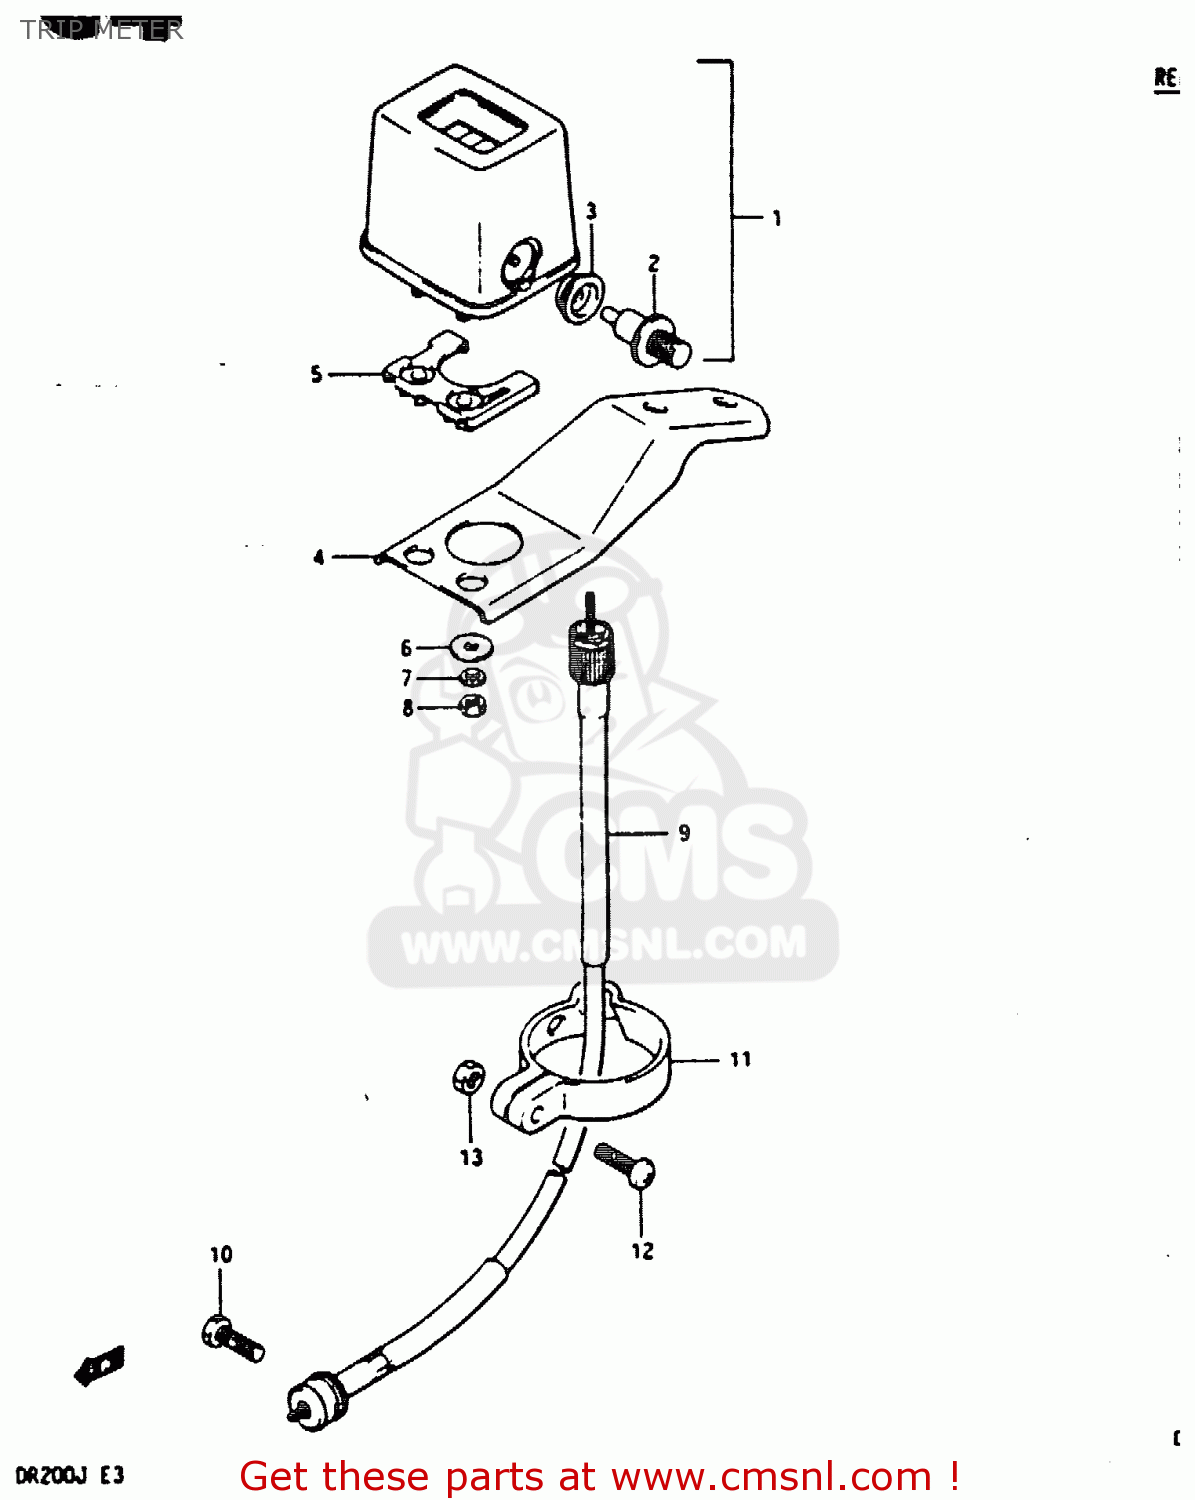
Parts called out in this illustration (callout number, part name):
1	TRIP METER
2	KNOB,TRIP METER
3	COVER,TRIPMETER KNOB
4	BRACKET,TRIPMETER
5	CUSHION,TRIPMETER
6	WASHER,METER
7	LOCK WASHER
8	NUT
9	CABLE ASSEMBLY,SPEEDOMETER
10	BOLT
11	CLAMP,SPEEDOMETER CABLE
12	SCREW
13	NUT ,5MM
